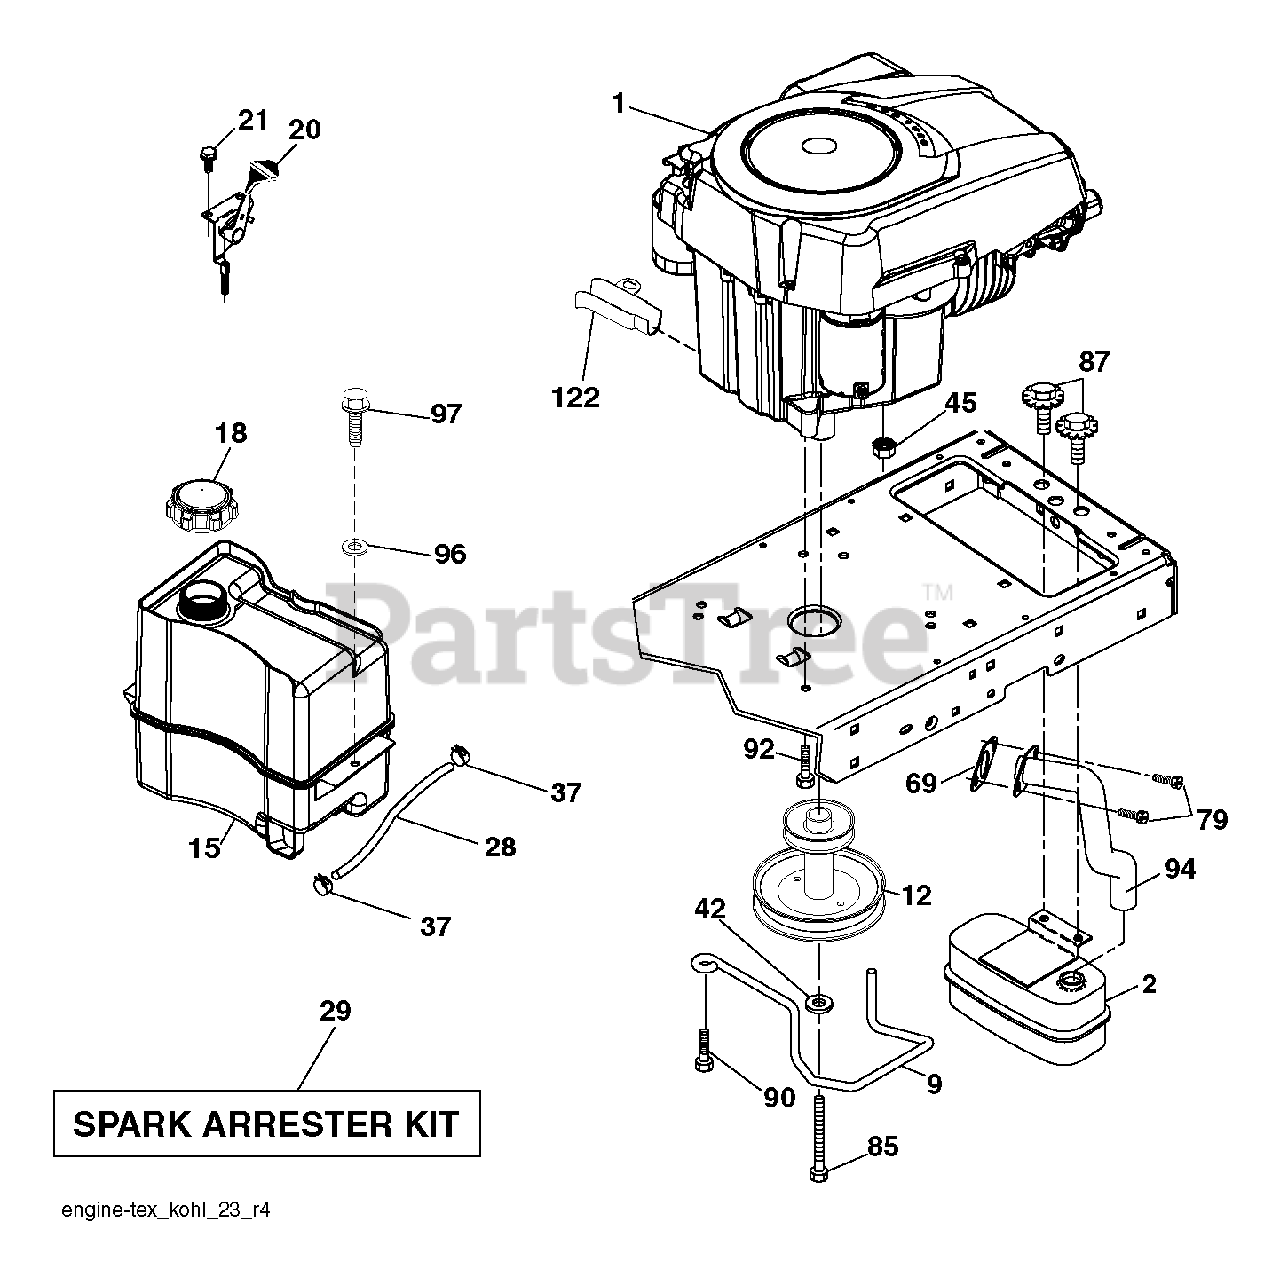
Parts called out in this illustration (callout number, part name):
2	MUFFLER.ASM.SNGL.XTNDED.DFLCTR
9	KEEPER.BELT.ENGINE.3.25 (3 2)
12	PULLEY ENGINE
15	TANK.ASSEMBL.2.5GAL.NON-EPA
18	CAP ASM.FUEL.2.25"FR.
20	CONTROL.TH/CK.COBRA.KO
21	SCREW.#10 X 0.750.BOS
28	LINE.FUEL.20"FRONT.EMI
29	KIT.SPARK ARRESTOR 794945 B&S
37	HOSE CLAMP
42	LOCKWASHER
45	NUT
69	GASKET.EXHAUST.KOHLER
79	SCREW.SOCKET HD.5/16-1
85	BOLT HEX 7/16-20X4-1/4"
87	BOLT, 5/16-18 X 1 3/4
90	SCREW 3/8-16X1
92	SCREW 3/8-16X1
94	TUBE.EXHAUST.KOHLER.COURAGE
97	SCREW HEXWSHR 1/4-20X3/4
122	EXTENSION DRAIN OIL
